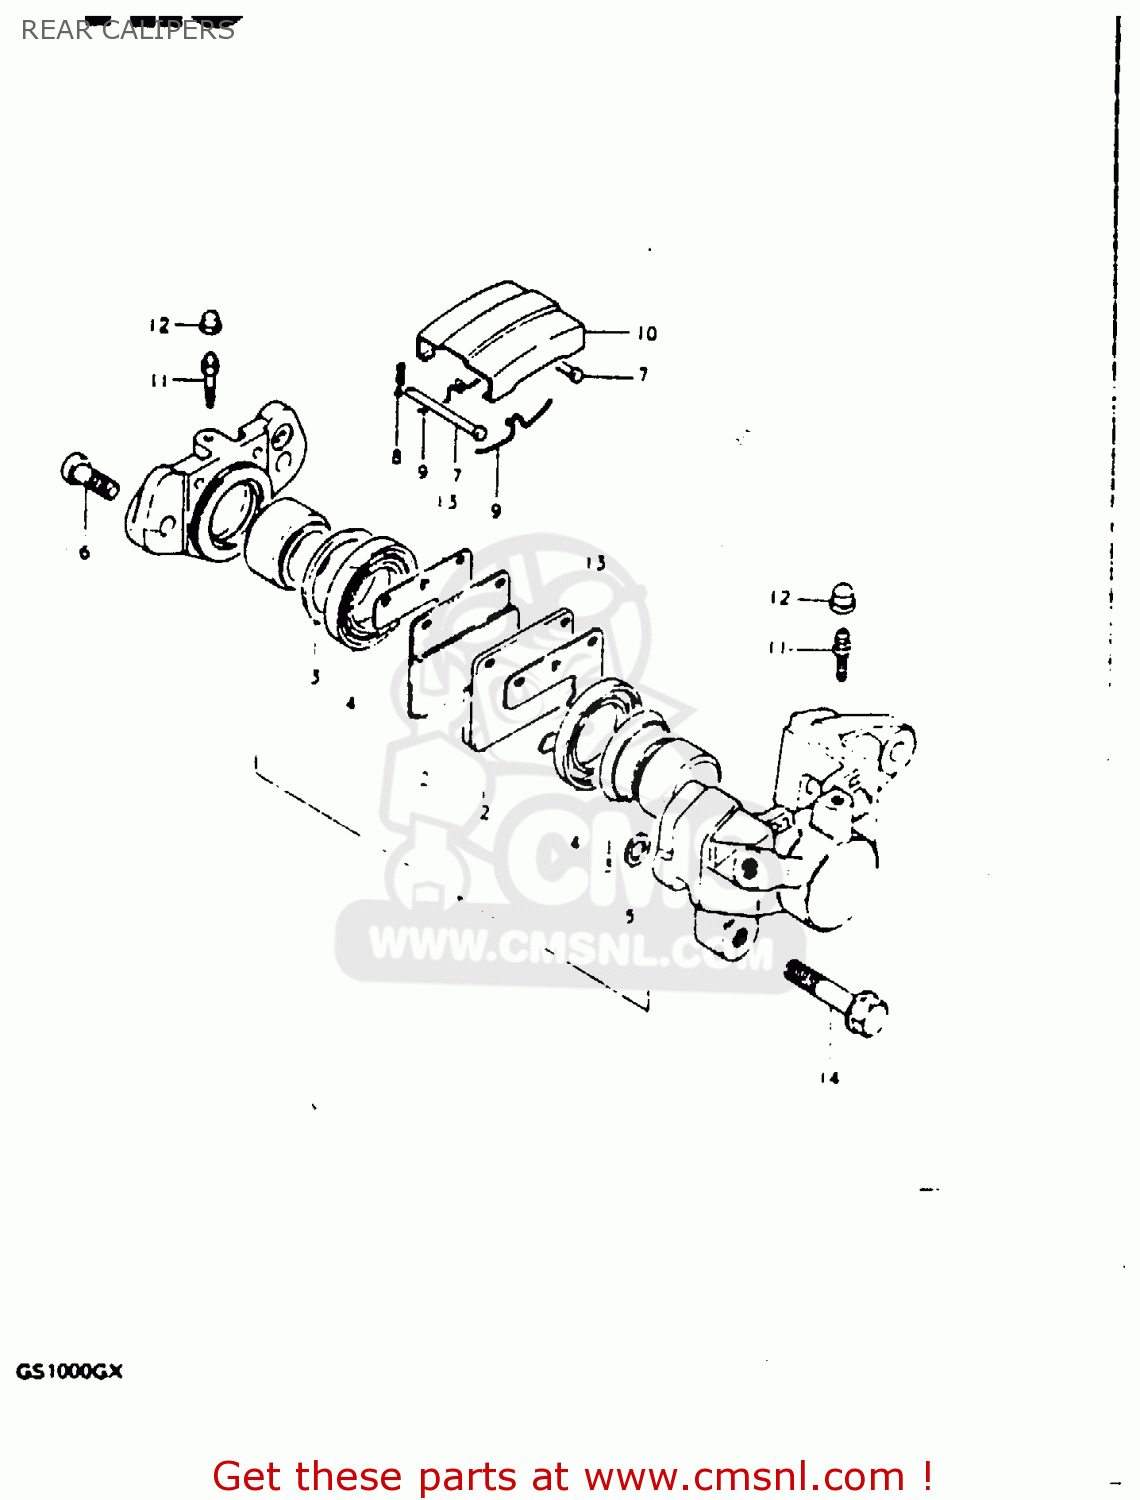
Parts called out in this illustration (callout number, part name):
1	PISTON SET
2	PAD,BRAKE
3	SEAL,PISTON
4	BOOT,PISTON
5	SEAL,PISTON
6	BOLT,HOUSING
7	PIN,PAD
8	CLIP,PAD PIN
9	SPRING
10	COVER,DUST
11	BLEEDER
12	CAP,BREATHER
13	SHIM,RR CALIPER
14	BOLT
